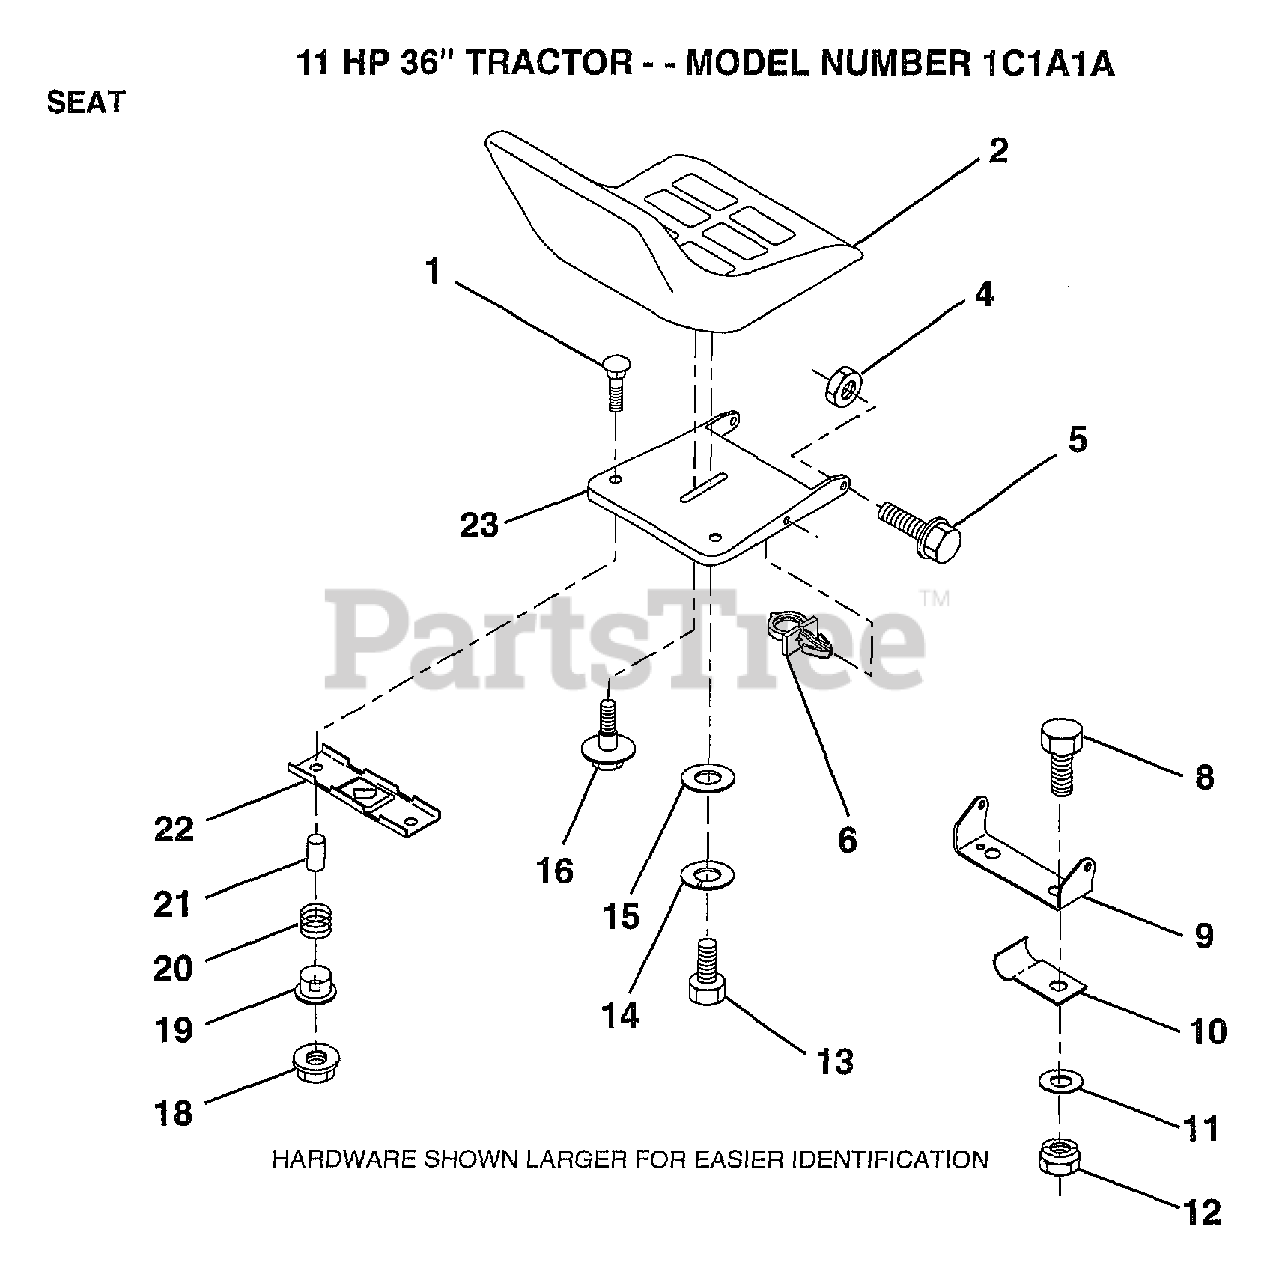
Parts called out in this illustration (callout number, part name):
5	BOLT.SHLD.5/16-18
6	CLIP PUSH - IN
9	BRACKET PVT SEAT
10	"CLIP,INSULATOR"
11	WASHER
12	NUT
13	BOLT
14	LOCKWASHER
15	WASHER
16	"BOLT,SHOULDER"
19	BUSHING
20	SPRING
21	SPLIT SPACER
22	BRKT SWITCH
